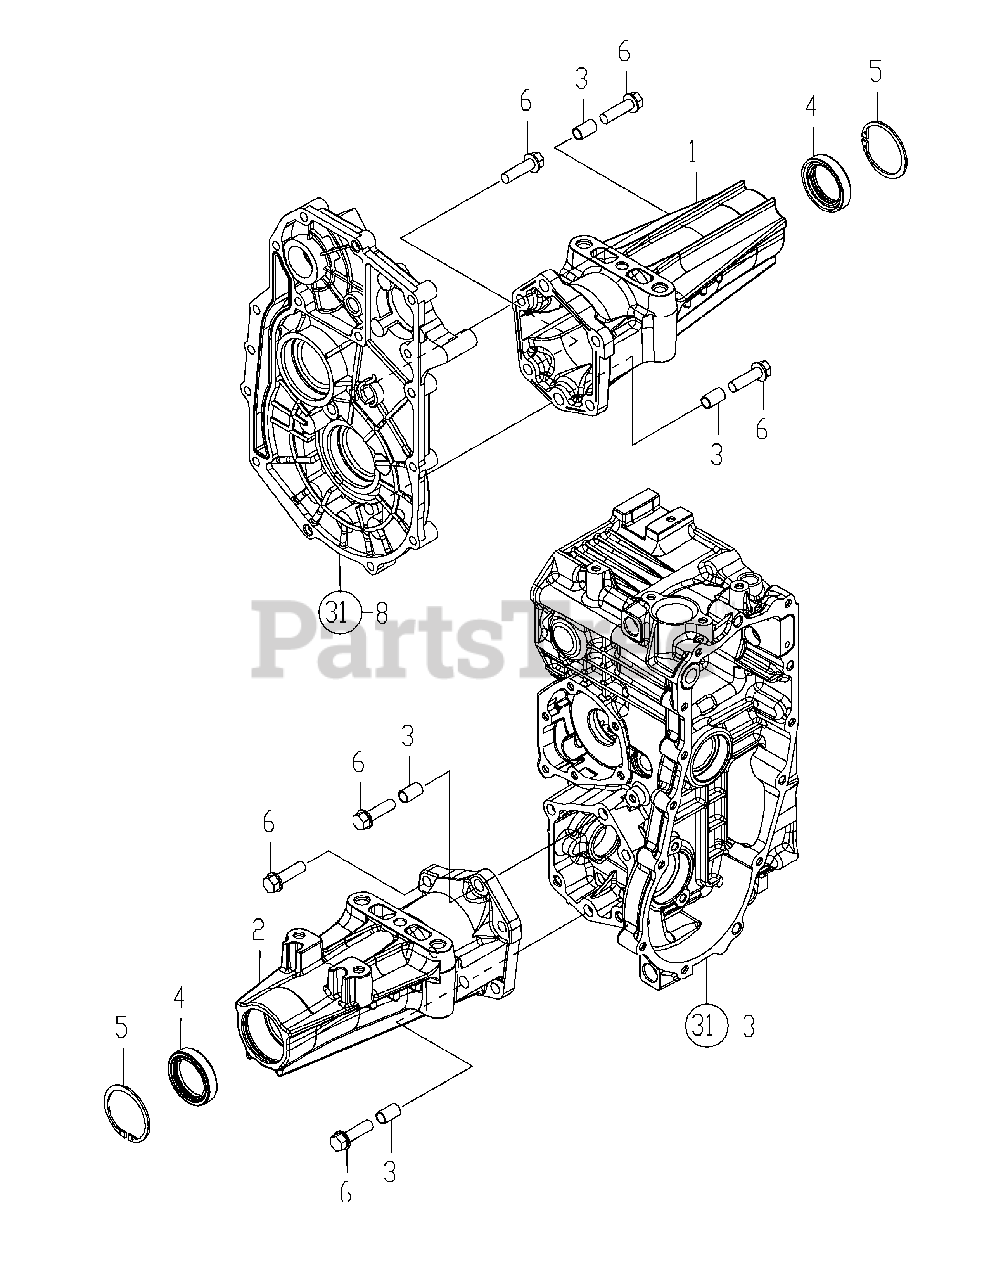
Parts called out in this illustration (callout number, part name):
1	HOUSING, REAR AXLE R
2	HOUSING, REAR AXLE
3	COLLAR, 10X12X20
4	SEAL, TC395511
